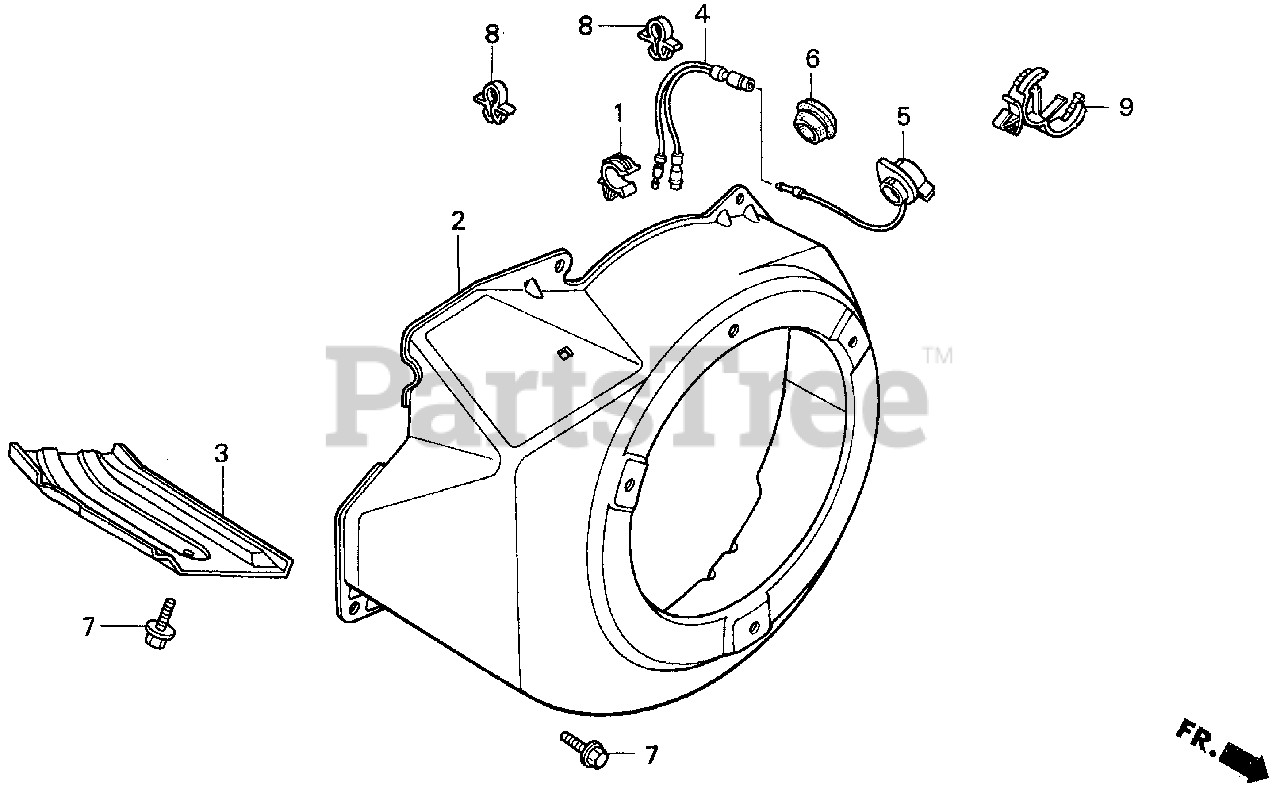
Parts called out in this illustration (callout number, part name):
1	CLIP, TUBE
2	COVER, FAN *R8* (BRIGHT RED)
2	COVER, FAN *NH1* (BLACK)
2	COVER, FAN *NH246* (LOOSY GRAY)
3	SHROUD
4	SUB-HARNESS
5	SWITCH ASSY., ENGINE STOP
7	BOLT, FLANGE (6X12) (CT200)
9	CLIP, WIRE HARNESS
